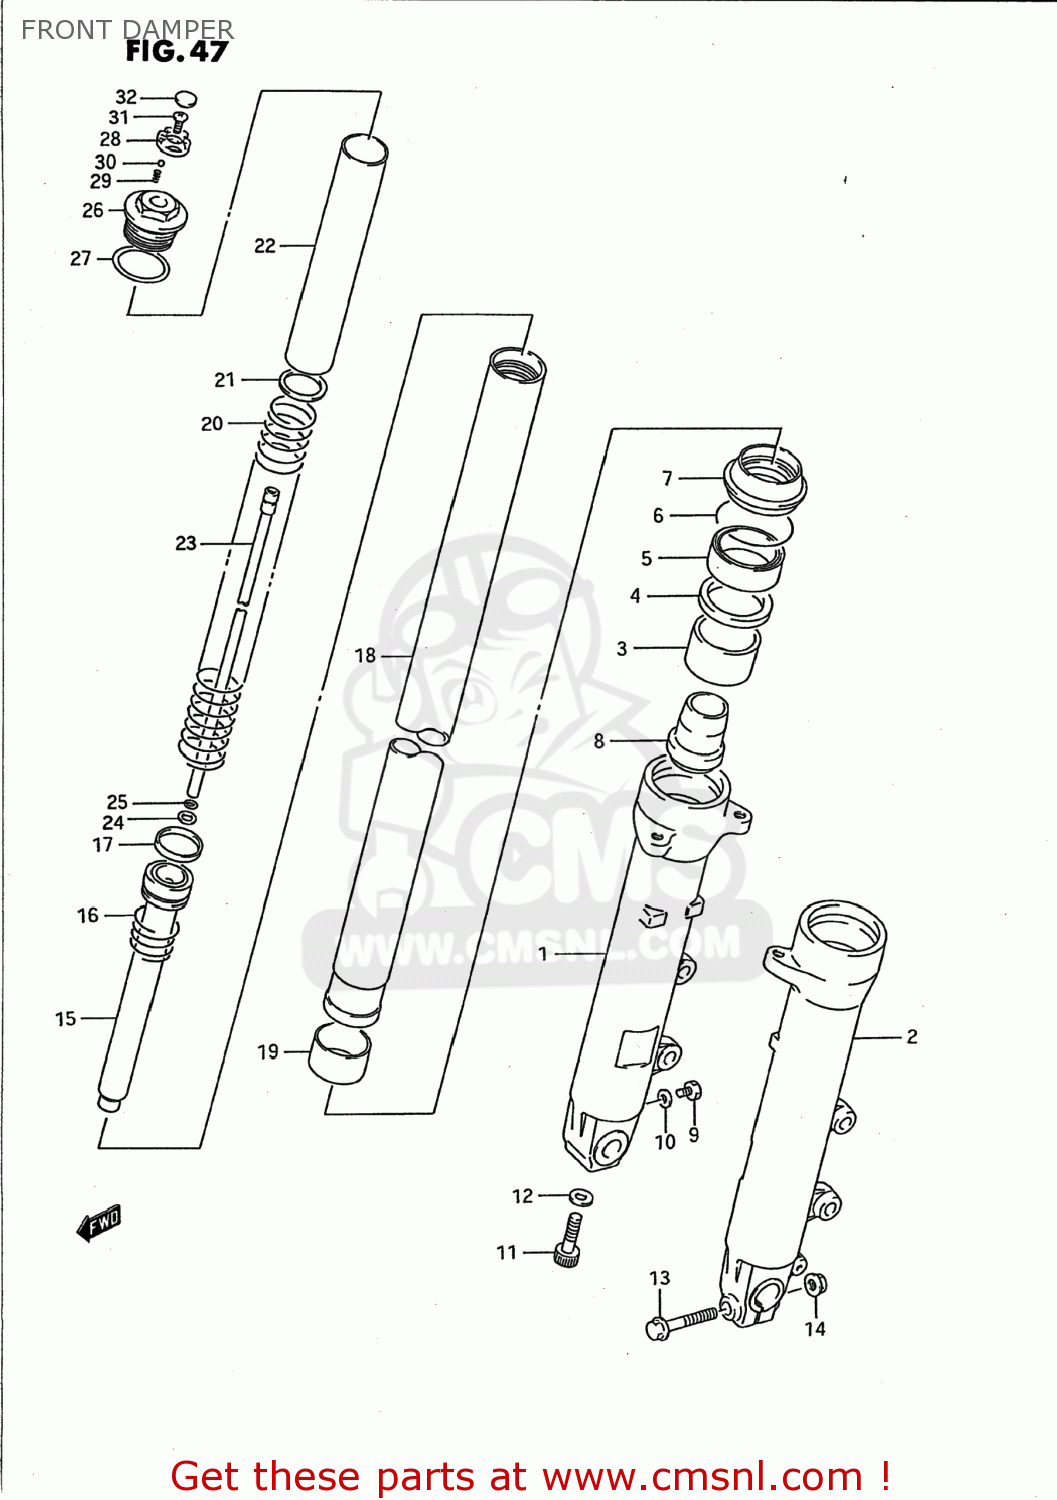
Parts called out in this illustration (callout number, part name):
1	TUBE,OUTER,RIGHT
2	TUBE,OUTER,LEFT
3	BUSH,GUIDE
4	SPACER,SEAL
5	SEAL,OIL
6	CIRCLIP,FORK OIL SEAL
7	BOOT
8	PIECE,OIL LOCK
9	BOLT(6X8)
10	GASKET,DRAIN,PLUG (NAS)
11	BOLT(8X27)
12	GASKET (NAS)
13	BOLT
14	NUT
15	SEAT,UNDER
16	SPRING,REBOUND
17	RING,PISTON
18	TUBE,INNER
19	BUSH,SLIDE
20	SPRING,MAIN
21	JOINT,SPRING
22	SPACER,SPRING
23	ROD,INNER
24	WASHER
25	O RING
26	BOLT,FORK
27	O RING
28	PLATE,ADJUSTER
29	SPRING
30	BALL
31	SCREW
32	CAP
